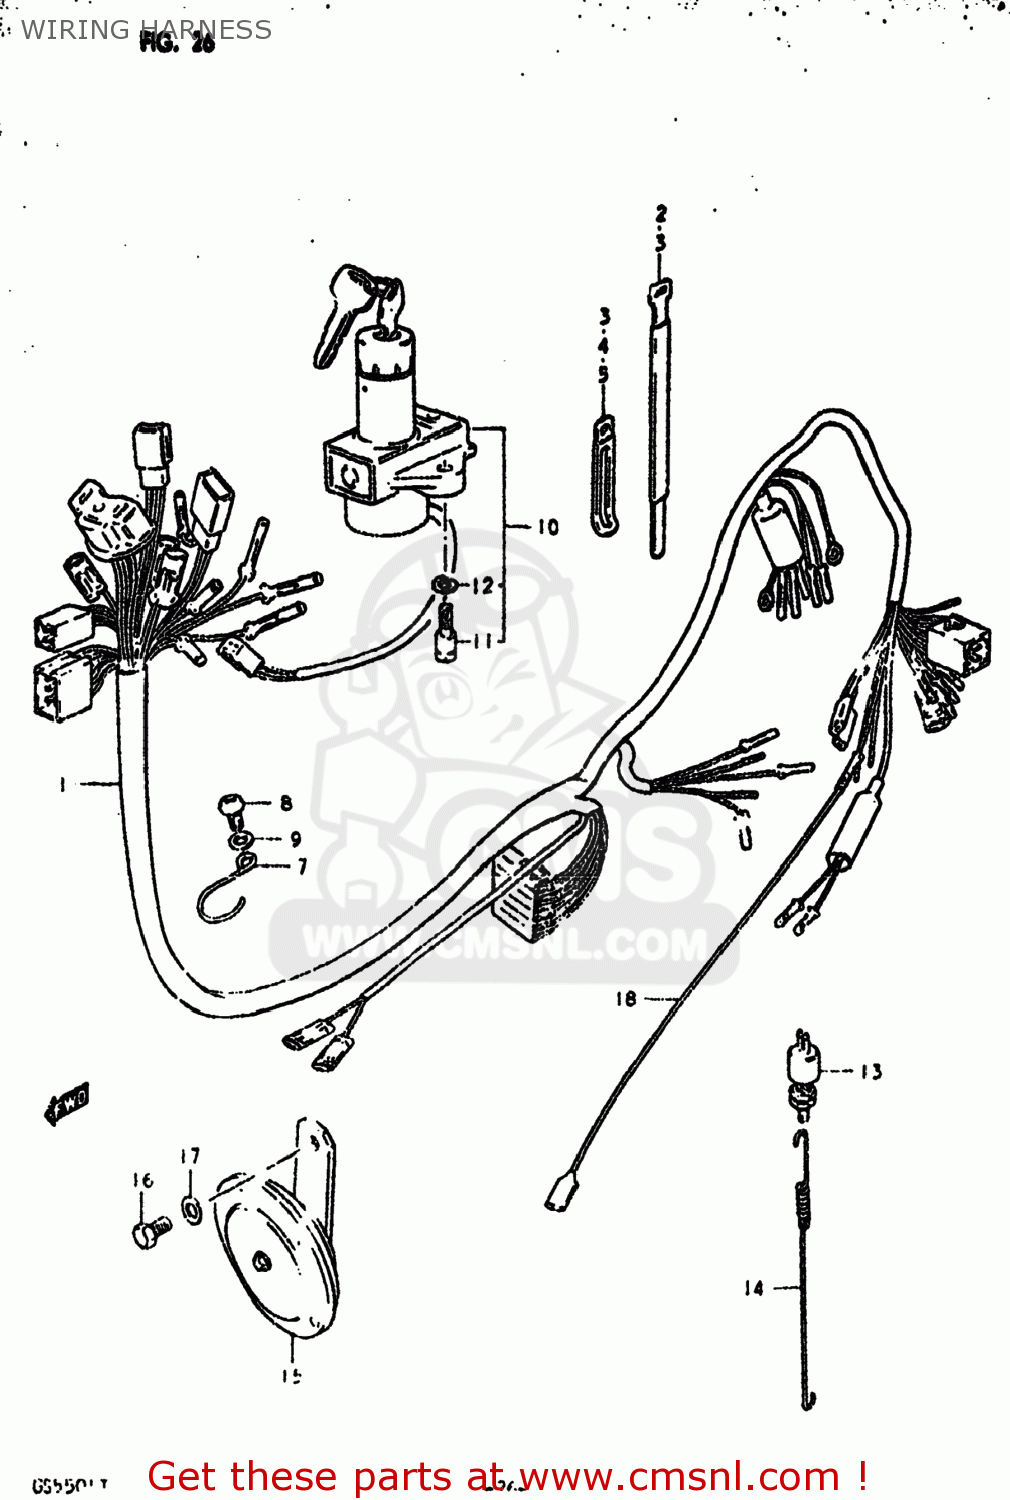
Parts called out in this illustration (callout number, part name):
1	HARNESS,WIRING
2	CLAMP
3	CLAMP(L:120)
4	CLAMP
5	CLAMP
6	CLAMP
7	GUIDE,WIRING HARNESS
8	SCREW 6X12
9	WASHER 6MM
10	LOCK ASSEMBLY,STEERING
11	BOLT
12	LOCK WASHER
13	SWITCH ASSY,BRAKE LAMP
14	SPRING
15	HORN ASSEMBLY,LOW PITCH
16	BOLT 8X12
17	WASHER
18	WIRE
